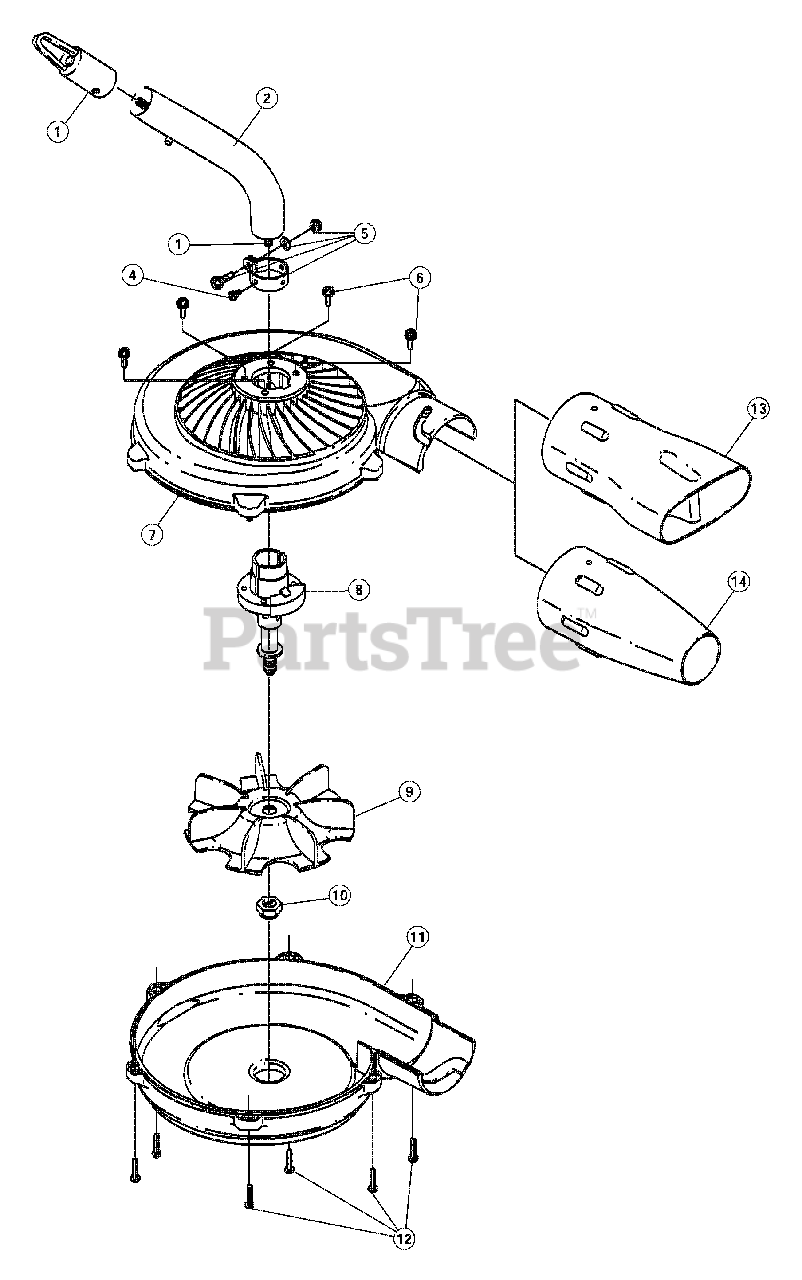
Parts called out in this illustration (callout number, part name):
1	Hanger
2	Drive Shaft Housing Assembly
3	Drive Shaft Assembly
4	Anti-Rotation Screw
5	Lower Clamp Assembly
6	Mounting Screw
7	Upper Housing
8	Bushing Housing Assembly
10	Nut and Washer
11	Lower Housing
12	Mounting Screw
13	Flare Nozzle
14	Concentrator Nozzle
